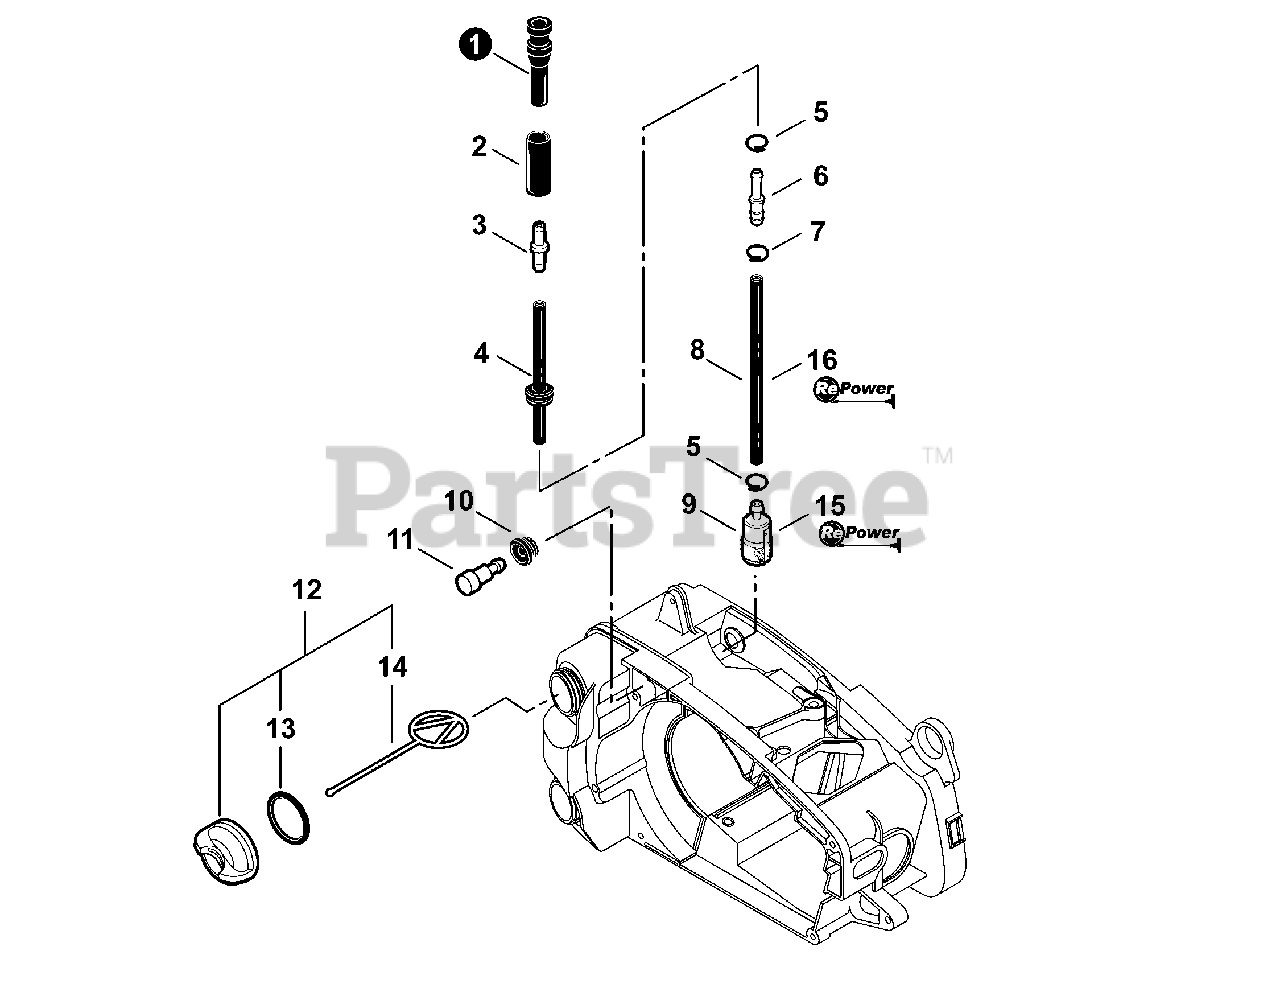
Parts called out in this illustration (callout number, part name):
1	LABEL, SPARK PLUG - BPM8Y
2	LABEL, SPARK PLUG - BPMR8Y
3	LABEL, CHOKE
4	LABEL, CHOKE
5	LABEL, CAUTION - HOT
6	LABEL, RECOIL STARTER
7	LABEL, MODEL SRM-225
8	LABEL, MODEL SRM-225I
9	LABEL, MODEL SRM-225SB
10	LABEL, MODEL SRM-225U
